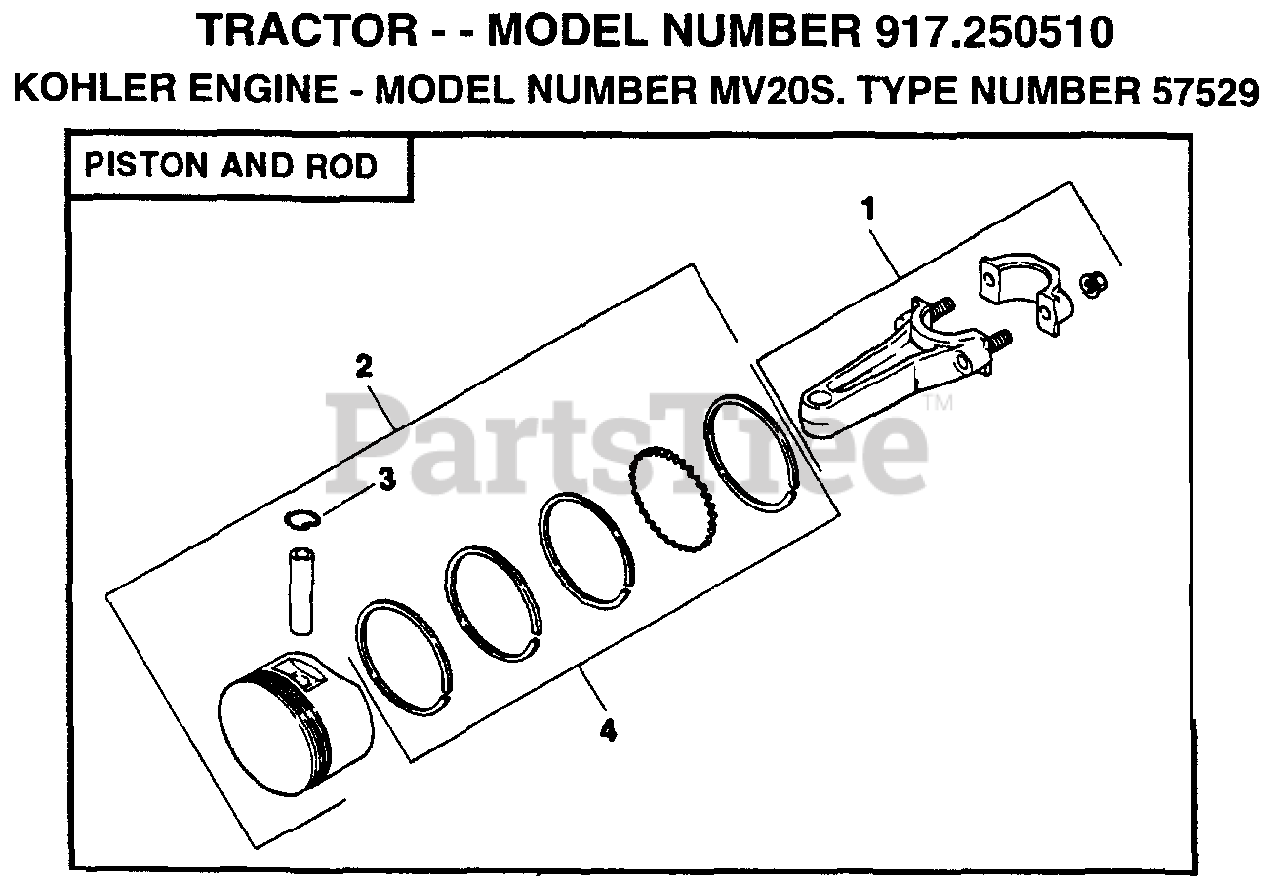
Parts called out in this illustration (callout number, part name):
1	CONNECTING ROD, STANDARD
2	PISTON WITH RING SET, STANDARD
2	PISTON WITH RING SET .003"
2	PISTON WITH RING SET .010"
2	PISTON WITH RING SET .020"
2	PISTON WITH RING SET .030"
3	RETAINER, PISTON PIN
4	RING SET, .003"
4	RING SET, .010"
4	RING SET, 020"
4	RING SET, .030"
